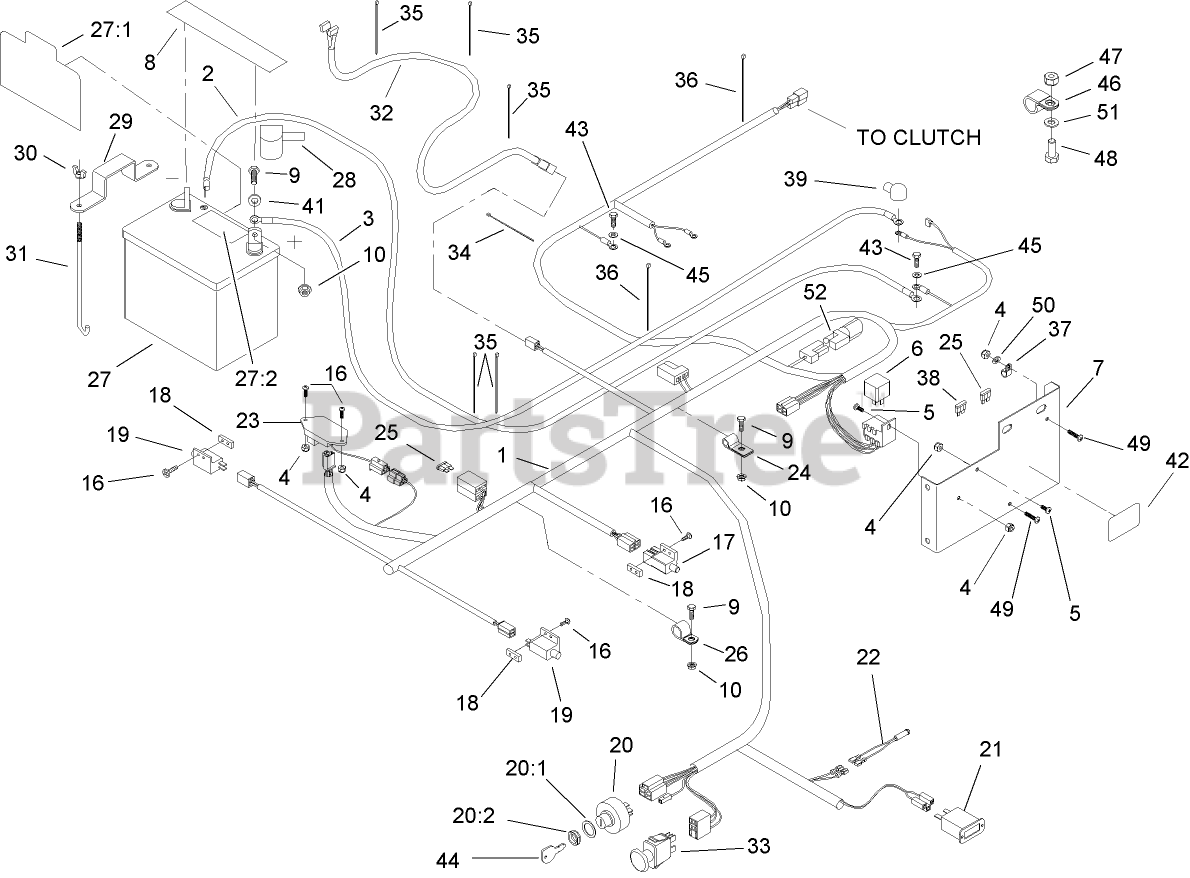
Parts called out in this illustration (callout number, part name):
1	Harness-Wire
2	WIRE-GROUND
3	WIRE-BATTERY, POSITIVE
4	NUT-LOCK, NI
7	PANEL-MOUNT, FUSE
8	Decal-Warning, Battery
9	SCREW-HH
10	NUT-HF
16	SCREW-PPH
17	SWITCH
18	PLATE-TAPPED
19	SWITCH-OPEN, NORMALLY
20	Key Switch ASM
20:1	WASHER-TOOTH, INTERNAL
20:2	NUT-HH
21	METER-HOUR
22	INDICATOR-LED, RED
23	MODULE-DELAY, SEAT
24	CLIP-LOOM
25	FUSE-BLADE TYPE, 20 AMP
27	BATTERY
27:1	Decal-Battery
27:2	Decal-Battery
28	INSULATOR-BATTERY
29	STRAP-HOLDDOWN
30	WINGNUT
31	BOLT-HOLDDOWN
32	HARNESS-WIRING, SEAT
33	SWITCH-DELTA
34	TIE-CABLE
35	TIE-PLASTIC
36	TIE-PLASTIC
37	CLIP-LOOM
38	FUSE-BLADE TYPE, 10 AMP
39	INSULATOR-SOLENOID
41	WASHER-FLAT
42	DECAL-RELAY / FUSE
43	SCREW-HH
44	KEY-IGNITION
45	WASHER-PLAIN
46	CLIP-LOOM
47	NUT-LOCK, NI
48	SCREW-HH
49	SCREW-HH
50	WASHER-FLAT
51	WASHER-FLAT
